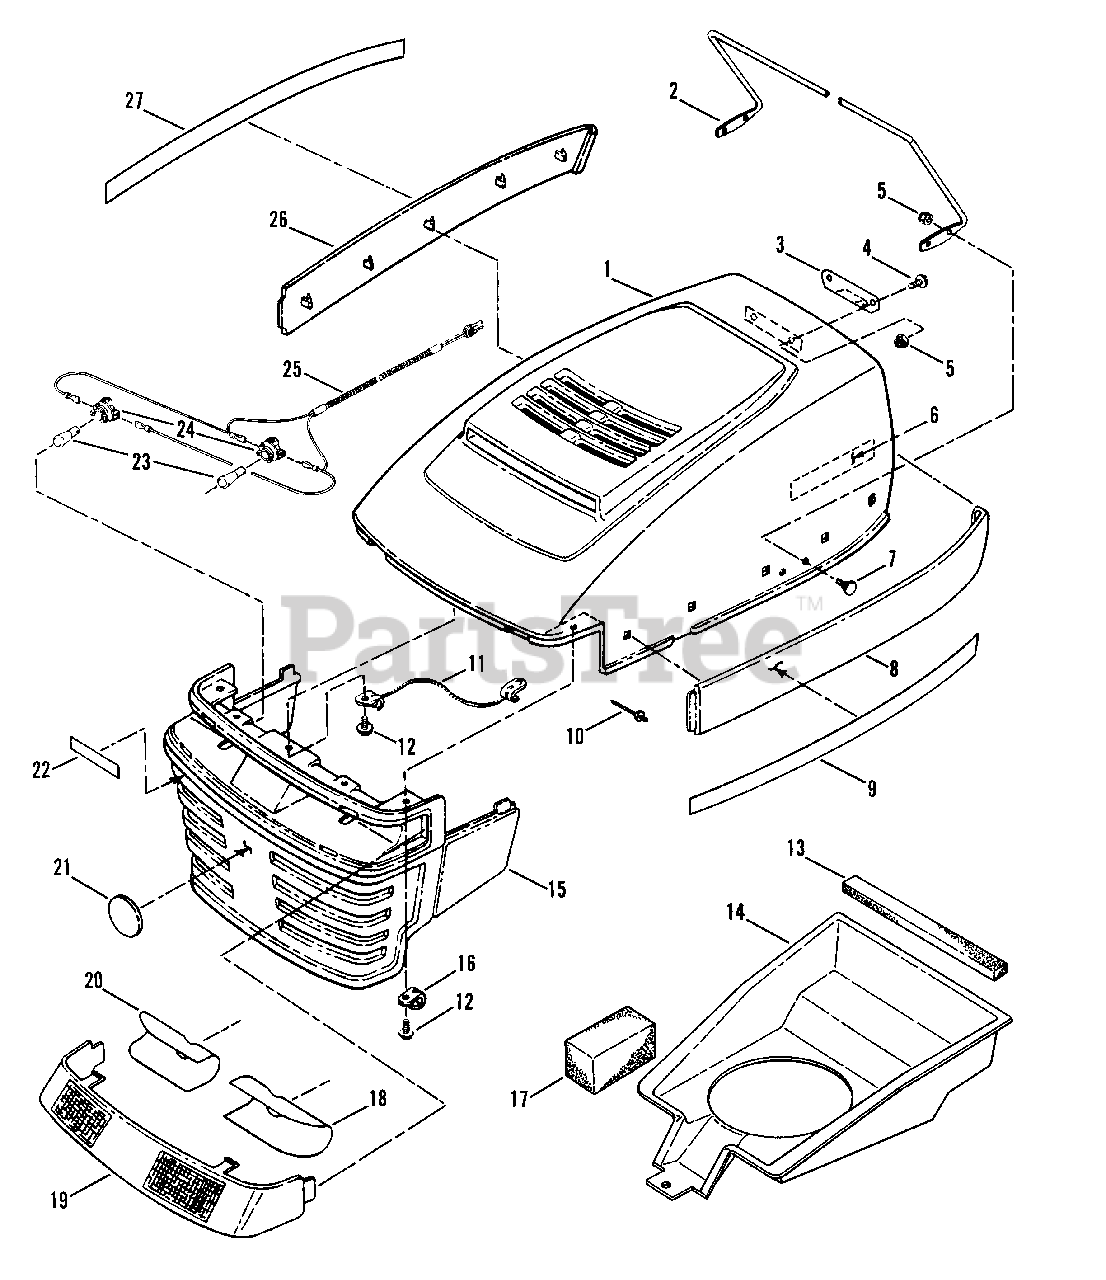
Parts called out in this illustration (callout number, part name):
1	KIT, Hood Assembly, Sloped Mozart (Contains most items on page)
2	ROD, Hood Support
3	LATCH, Spring
4	SCREW, 1/4-20 x 5/8" Truss Head
5	NUT, 1/4-20 Hex (Nyloc)
6	LOGO - SNAPPER (Chrome)
7	BOLT, 1/4-20 x 5/8" Carriage
8	PANEL, Hood (Left Side) (No longer available)
9	DECAL, Hood LX130H (Left Hand)
9	DECAL, Hood LX150H (Left Hand)
9	DECAL, Hood RX150H (Left Hand)
9	DECAL, Hood LX170H (Left Hand)
10	RIVET, 1/8" Pop
11	LANYARD, Hood 17.5"
11	LANYARD, Hood 14.5"
12	SCREW, M4.8 x 1.59 x 16.00mm Special
13	FOAM, 1/2" x 3/4" x 14.25" (No longer available)
14	PLENUM
15	GRILLE, Hood
16	CLIP, "J"
17	FOAM, 2" x 2" x 3.5"
18	DECAL, Reflect (Left Side)
19	LENS
20	DECAL, Reflect (Right Side)
21	LOGO, Convertible (No longer available)
22	LOGO - SNAPPER, 4" (Chrome)
23	BULB, Headlights 1141
24	SOCKET, Headlight Bulb
25	HARNESS, Headlight Wiring
26	PANEL, Hood (Right Side) (No longer available)
27	DECAL, Hood LX130H (Right Side)
27	DECAL, Hood LX150H (Right Side)
27	DECAL, Hood RX150H (Right Side)
27	DECAL, Hood LX170H (Right Side)(No longer available)
